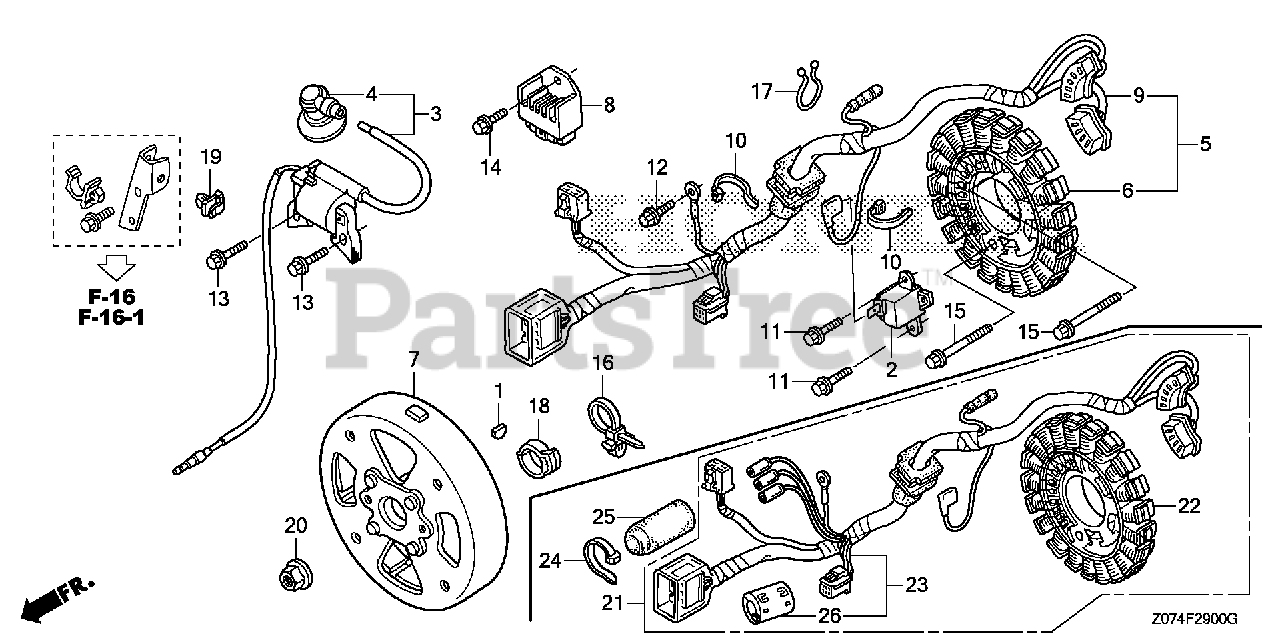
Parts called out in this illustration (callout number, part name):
1	KEY, SPECIAL
2	GENERATOR, PULSE
3	COIL ASSY., IGNITION
4	CAP ASSY., NOISE SUPPRESSOR
5	STATOR ASSY.
8	RECTIFIER ASSY.
9	WIRE HARNESS ASSY., GENERATOR
10	BAND, NYLON
11	BOLT, FLANGE (5X14) (CT200)
12	BOLT, FLANGE (5X10)
13	BOLT, FLANGE (6X20) (CT200)
14	BOLT, FLANGE (6X16)
15	BOLT, FLANGE (5X32) (CT200)
16	BAND, WIRE HARNESS (150MM) (Honda Code 1352103). (BLUE)
17	BAND, TUBE
18	CLIP, WIRE HARNESS
19	CLIP, WIRE HARNESS
20	NUT, FLANGE (12MM)
